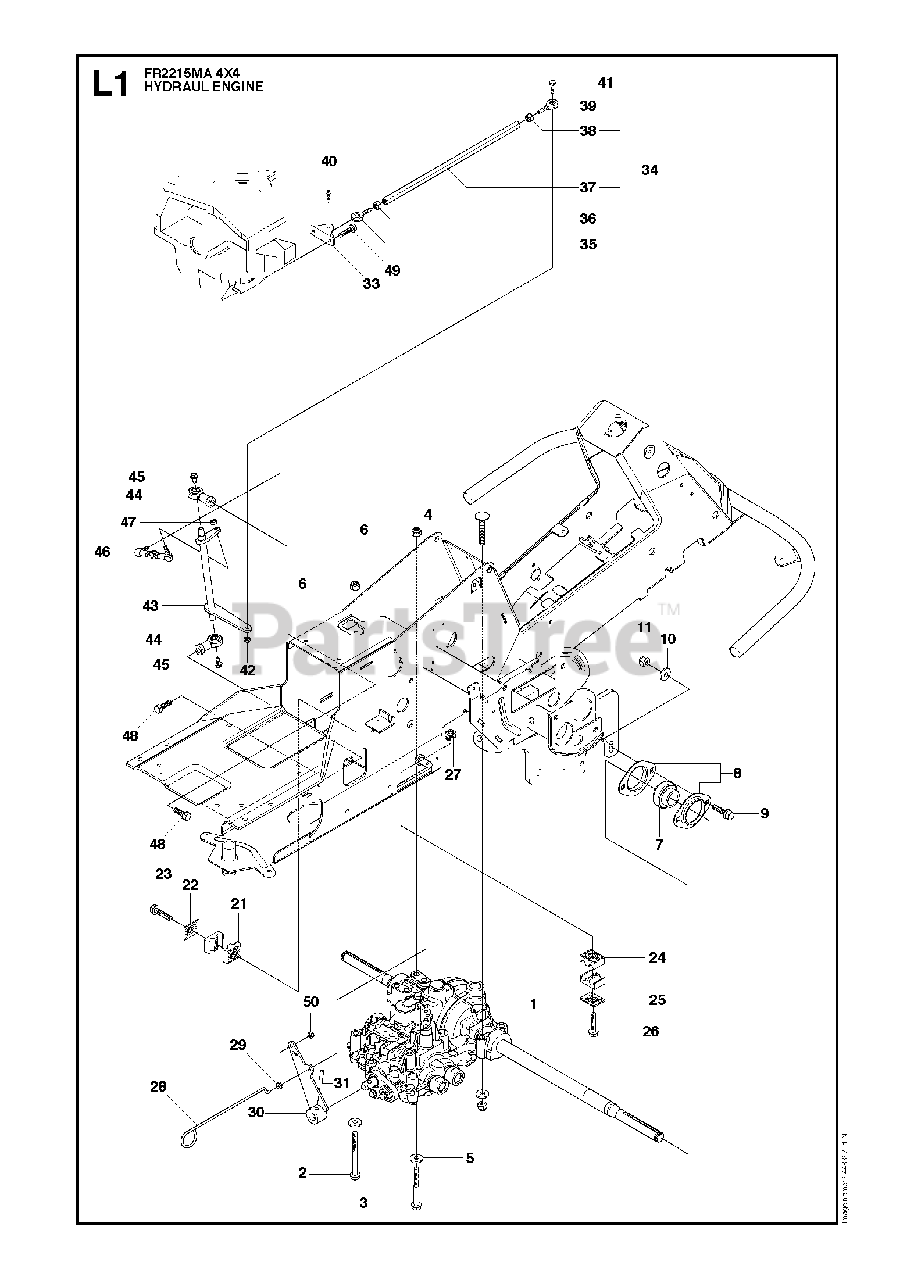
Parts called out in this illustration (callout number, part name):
1	TRANSMISSION
5	WASHER BRB 8.4X17
6	LOCKNUT M8
8	BEARING HOUSING
9	BOLT
10	WASHER BRB 8.4X17
11	LOCKNUT M8
21	PIPE CLAMP
24	PIPE CLAMP
25	COVER PLATE
26	SCREW EHHFM
29	FUEL TANK BUSHING
35	LINK
36	NUT
37	ROD
38	NUT
39	LINK
42	NUT FLANGE - M6
45	SCREW EHHFM
46	ADJUSTING ROD
47	NUT FLANGE - M6
48	SCREW M10X25
50	LOCKNUT M6
